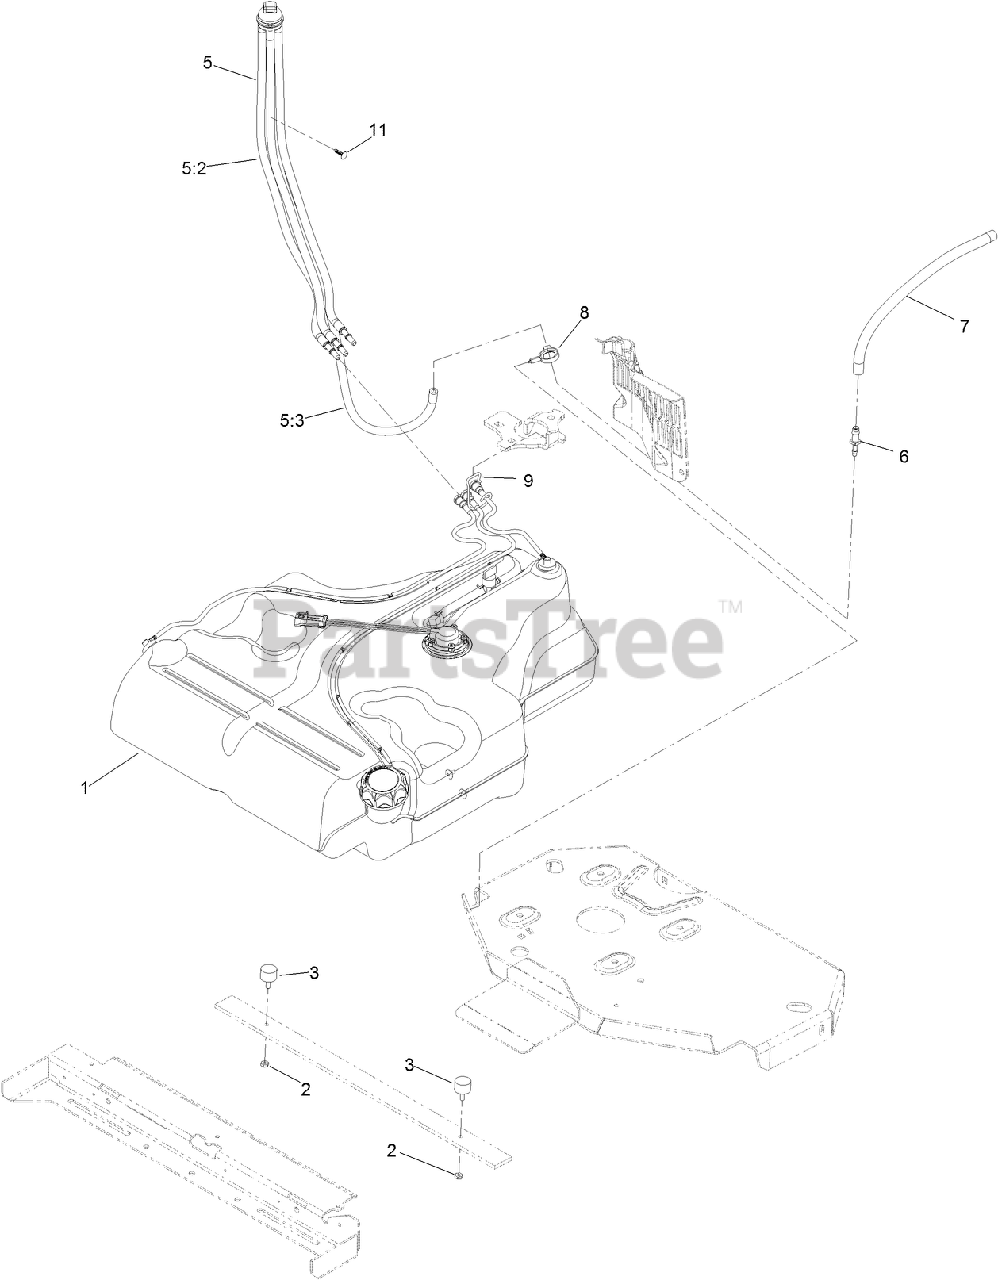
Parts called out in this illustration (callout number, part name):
1	FUEL TANK ASM
2	NUT-JAM
3	BUMPER
5	FUEL MANIFOLD VENT ASM
5:2	HOSE-FUEL
5:3	HOSE-FUEL
6	FITTING-STRAIGHT
7	HOSE-FUEL
8	CLAMP-HOSE
9	RETAINER-LINE, VAPOR
11	PLUG-PLASTIC
